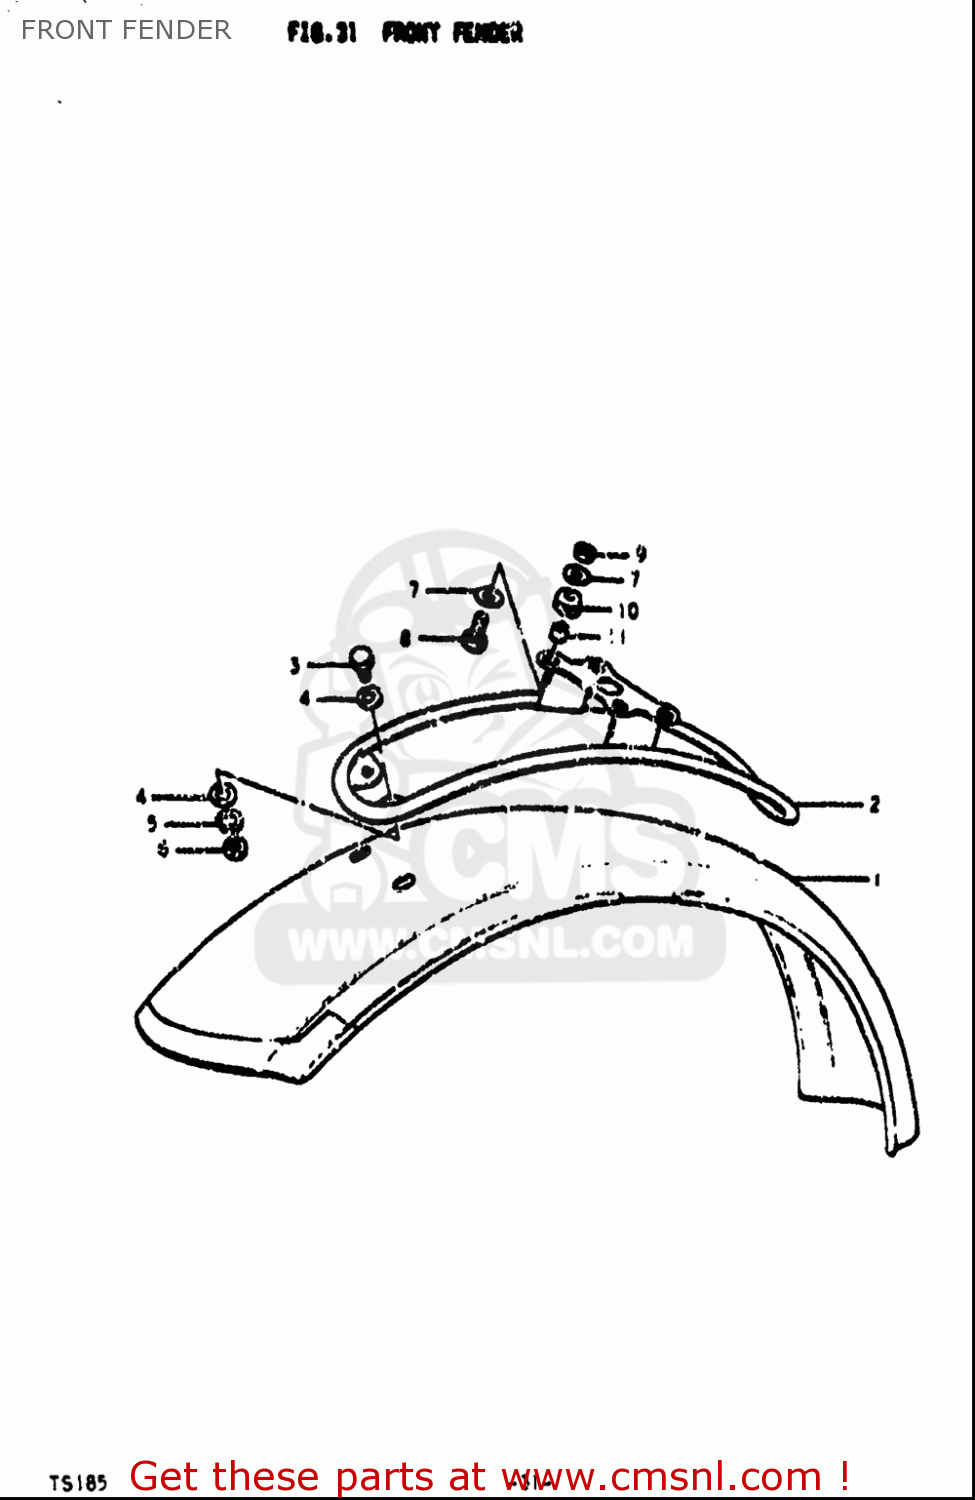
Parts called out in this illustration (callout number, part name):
3	BOLT(6X14)
4	WASHER
5	WASHER,LOCK
6	NUT
7	WASHER(6.5X20X1.2)
8	BOLT
9	NUT
10	CUSHION
11	SPACER(6.1X9X7.5)
